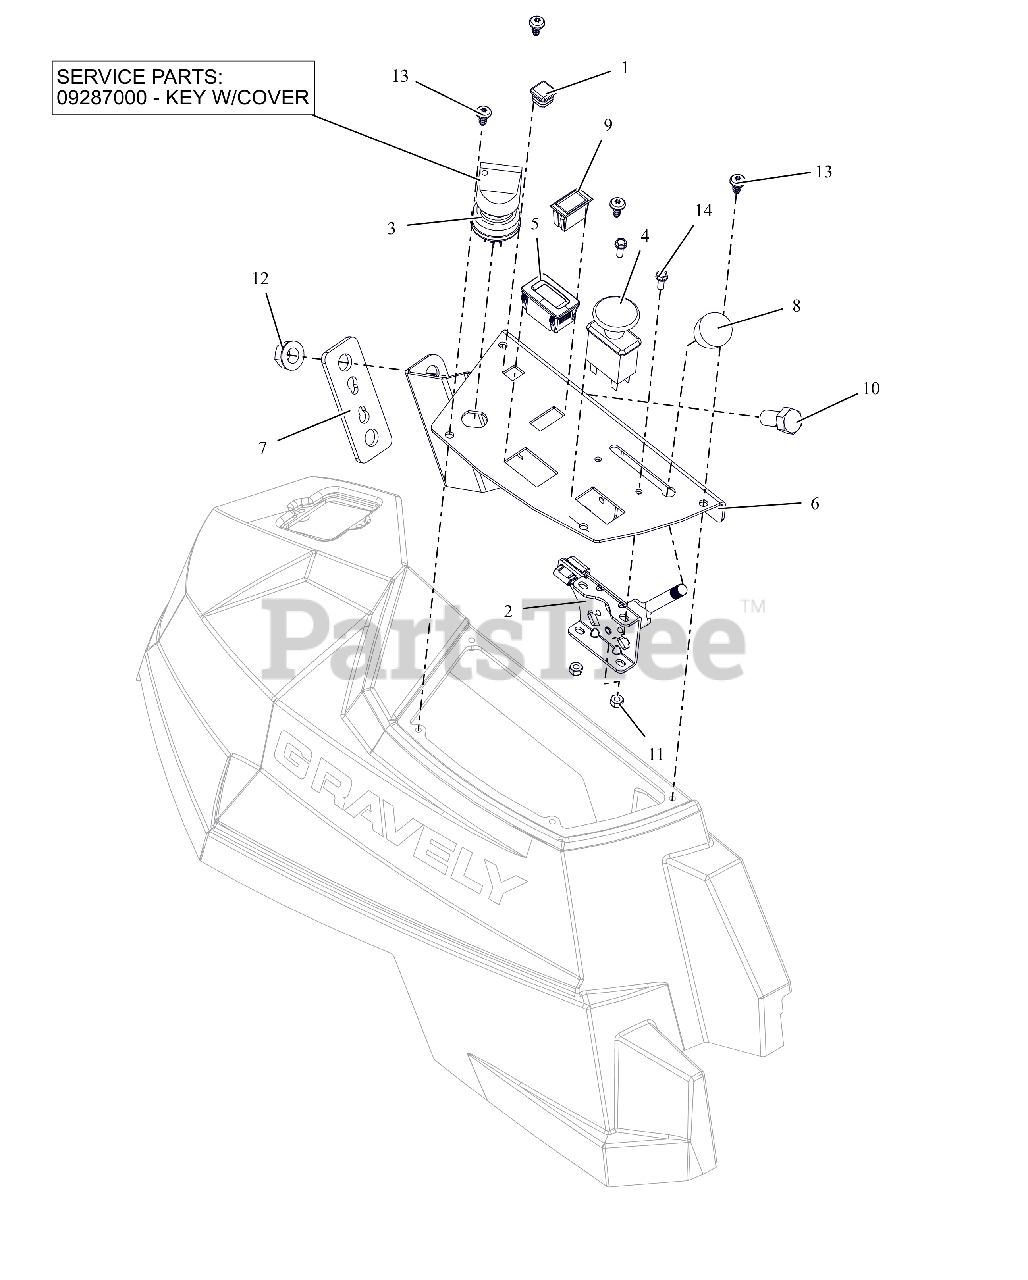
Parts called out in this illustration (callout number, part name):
1	PLUG, 5/8" SQ BLACK (14-20GA)
2	CABLE, PRO THROTTLE CONTROL
3	SWITCH, IGNITION
3	KEY, W/ SHIELD
4	SWITCH, CLUTCH
5	HOUR METER
6	PANEL, HD CONTROL
7	PLATE, CONTROL PANEL SPACER
8	KNOB-CONTROL-BLACK .38-16X.50
9	SWITCH,BLANK
10	BLT, HEX .50-13X1.00 G5 ZCC
11	NUT-LK-NYL #10-24 G2 ZCC
12	NUT-LK-TOP-FLG .500-13 GF ZCC
13	SCR-PAN .25-15X.50 6L H/LZB500
14	BLT, HWH #10-24X.50 ZCC
